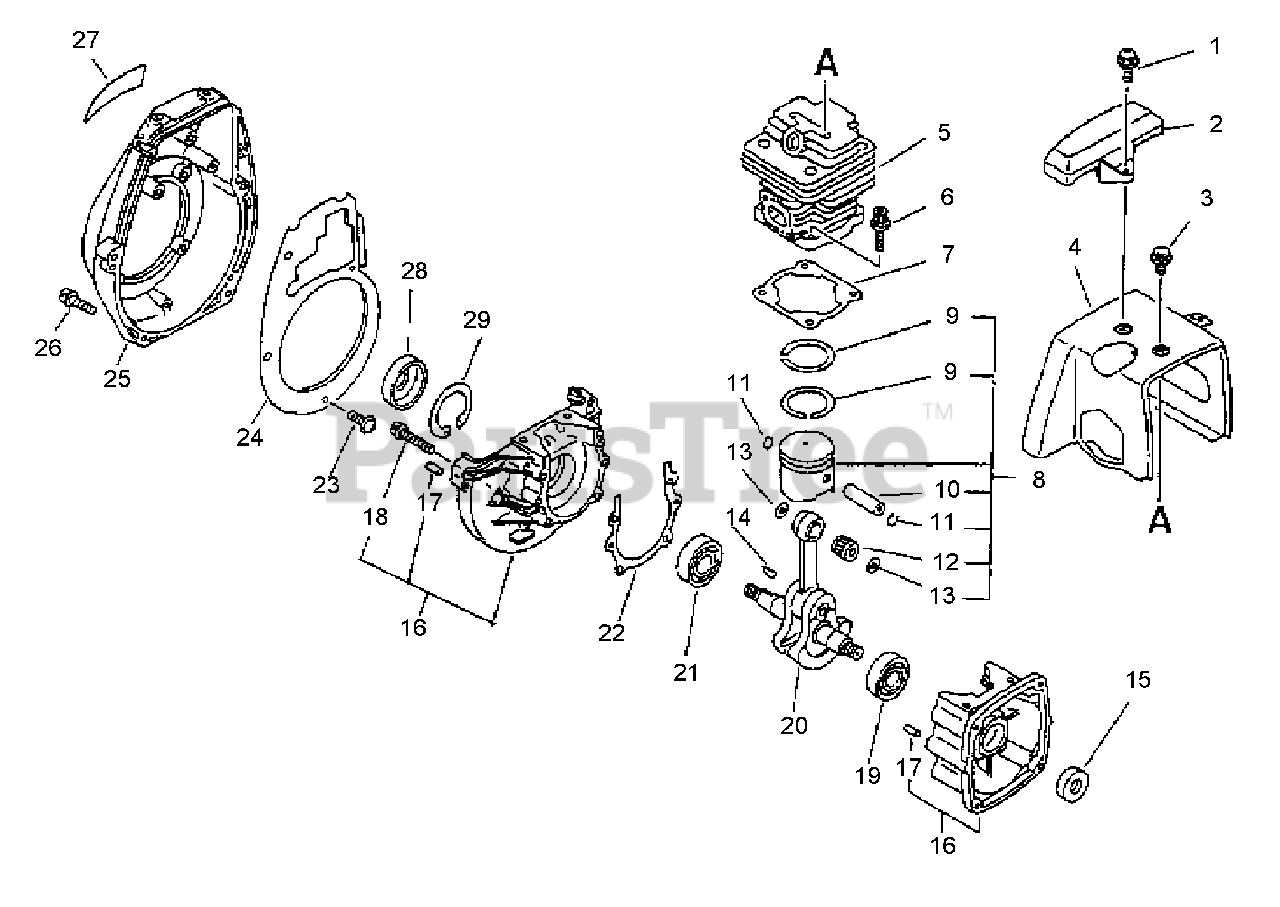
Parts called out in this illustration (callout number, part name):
1	SCREW 5×14
2	GUARD, TOP
3	SCREW 5×10
4	COVER, ENGINE
5	CYLINDER
6	BOLT 5×20
7	GASKET, CYLINDER
8	PISTON KIT
9	RING, PISTON
10	PIN, PISTON
11	RING, SNAP 8
12	BEARING, NEEDLE 10
13	WASHER, THRUST
14	KEY, WOODRUFF
15	SEAL, OIL 12
16	CRANKCASE KIT
17	PIN, LOCATING 5×10
18	BOLT 5×30
19	BEARING, BALL - 6201 C3
20	CRANKSHAFT ASSY
21	BEARING, BALL 6202
22	GASKET, CRANKCASE
23	SCREW 4×10
24	GUIDE, AIR
25	CASE, FAN
26	BOLT 5×25
27	LABEL - MODEL
28	SEAL, OIL 18
29	RING, SNAP 35
